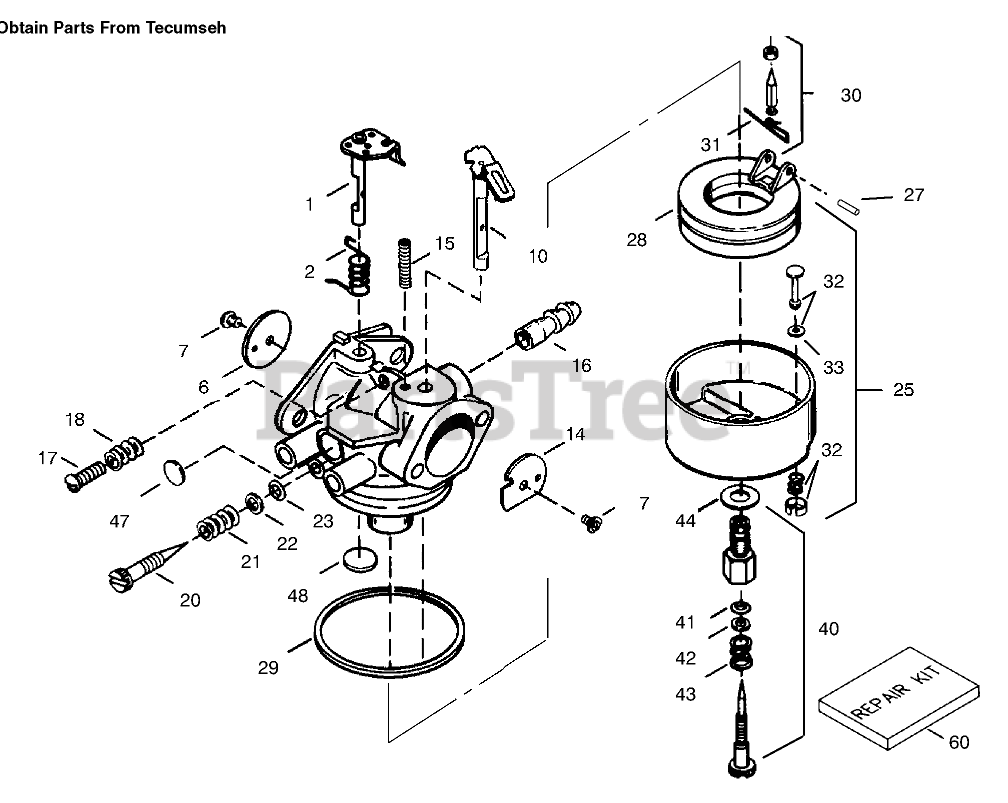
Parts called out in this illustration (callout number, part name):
1	Throttle Shaft and Lever ASM
2	Spring-Return, Throttle
6	Shutter-Throttle
7	Screw-Shutter
10	Choke Shaft and Lever ASM
14	Shutter-Choke
15	Spring-Positioning, Choke
16	Fitting-Fuel
17	Screw-Throttle Crack Screw / Idle Speed
18	Spring-Tension
20	Screw-Idle Mix
21	Spring-Tension
23	"O"Ring
25	Float Bowl Assembly (Incl. Ref. #32 & 33)
27	Shaft-Float
28	Float
29	O Ring-Bowl, Float
30	Inlet Needle, Seat & Clip Asm (Incl. Ref. #31)
31	Clip-Spring
32	Drain Assembly (Incl. Ref. #33)
33	Gasket-Plunger, Drain
40	Adjustment Screw Asm (Incl. Ref. #43, 44, 41 & 42)
41	"O"Ring
44	Washer-Bowl Nut
47	Plug-Welch, Idle Mixture Well
48	Plug-Welch, Atmospheric Vent
60	Kit-Repair
